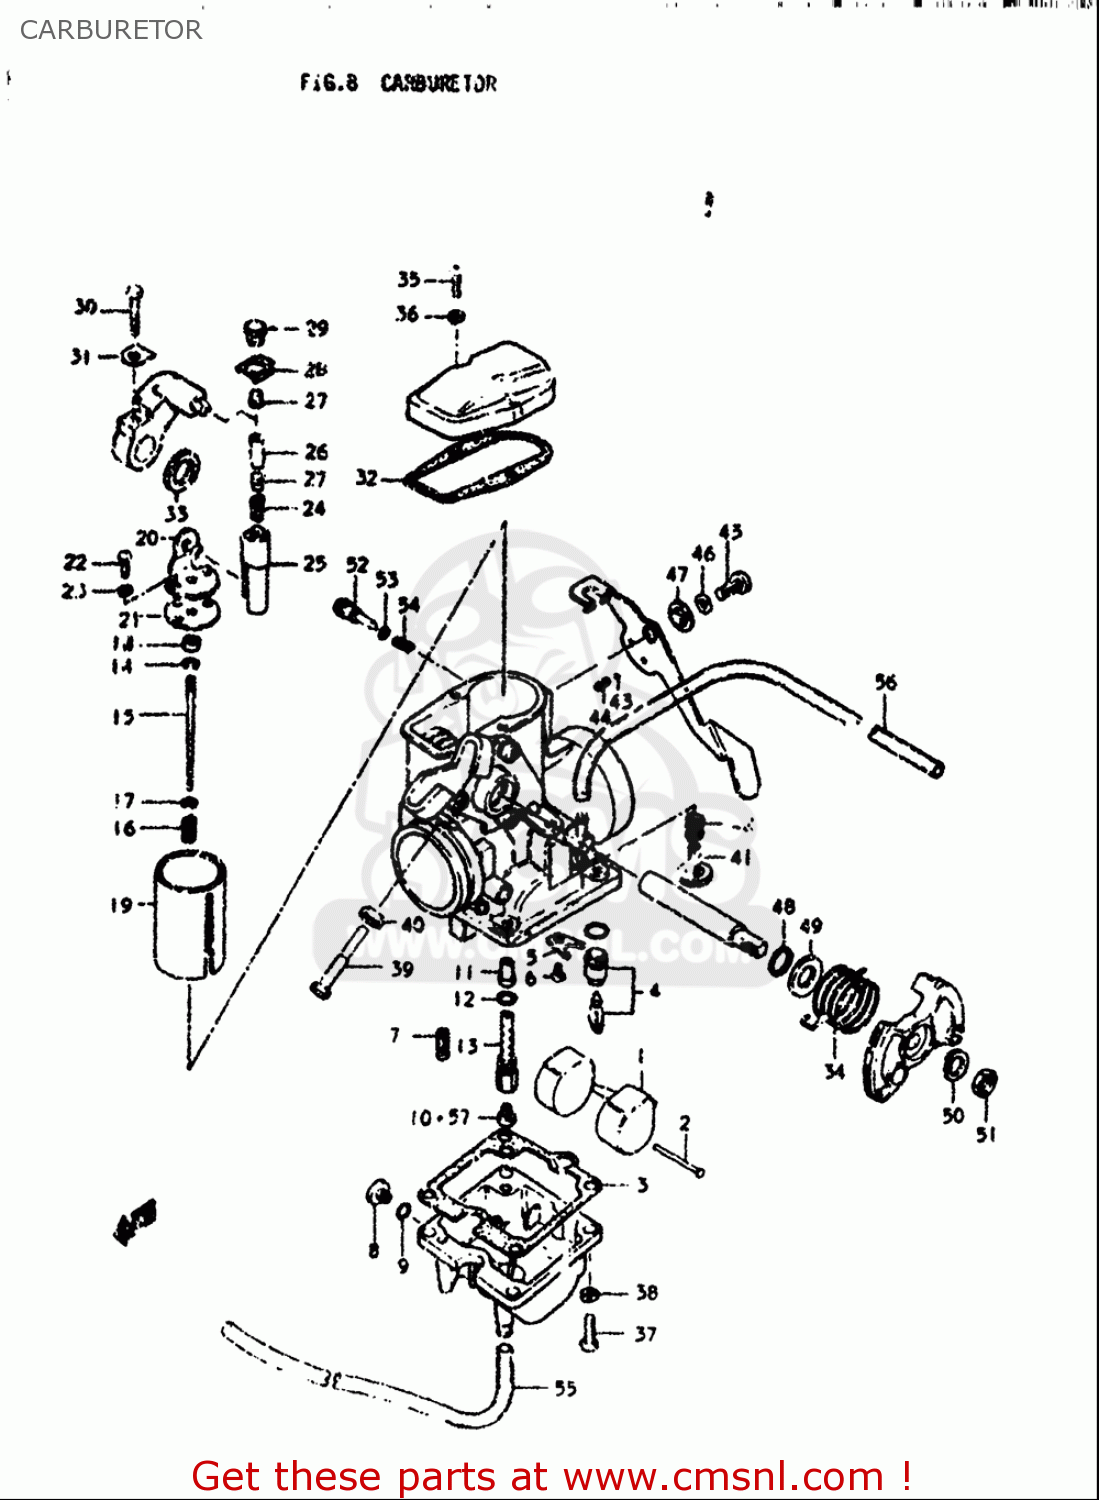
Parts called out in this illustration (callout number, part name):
1	FLOAT
2	PIN,FLOAT
3	GASKET,FLOAT CAHMBER (NAS)
4	VALVE ASSY,NEEDLE
5	PLATE
6	SCREW 4X6
7	JET,PILOT(25)
8	SCREW
9	O RING
10	JET,MAIN(125)
12	O RING
14	CLIP
16	SPRING
17	WASHER,JET NEEDLE
18	RING
22	SCREW
23	WASHER,LOCK
24	SPRING,CARBURETOR
29	SCREW
32	GASKET,TOP (NAS)
35	SCREW 4X16
36	WASHER,LOCK
37	SCREW
38	WASHER,LOCK
39	SCREW
42	SPRING,THROTTLE SCREW
43	BALL,CARBURETOR
44	SPRING
45	SCREW
46	WASHER,LOCK
47	RING,CARBURETOR STARTER
48	SEAL
50	WASHER,LOCK
51	NUT
52	SCREW,PILOT AIR ADJUSTING
53	O RING
54	SPRING
56	HOSE(4.5X8.5X600)
